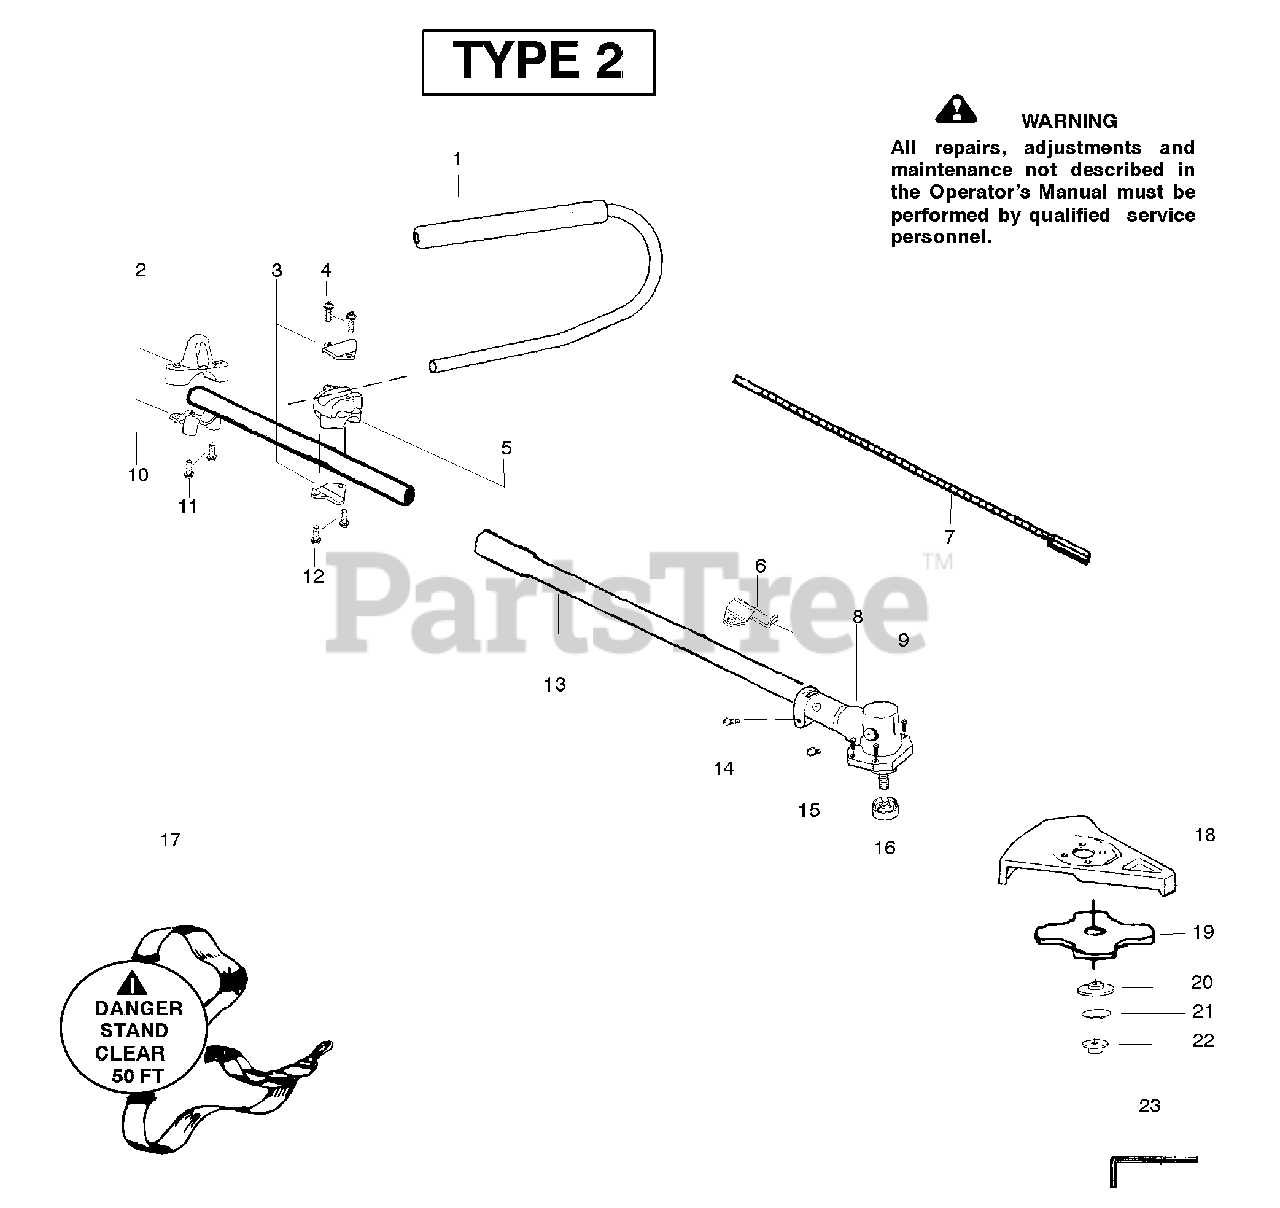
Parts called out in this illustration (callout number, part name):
1	Kit-Handlebar
2	Clamp-Harness Upper
3	Clamp-Bracket
5	Clamp-Handlebar (7/8")
5	Clamp-Handlebar (1")
6	Bracket-Shield
7	Flexshaft-Split boom
8	Assy-Gearbox
10	Clamp-Harness Lower
13	Assy.-Driveshaft
15	Screw-Alignment
16	Dust cup - Blade
17	Assy-Shoulder Strap
18	Kit-Blade Shield
19	Accy.-Weed Blade (8")
20	Washer-Blade Retaining
21	Washer-Belleville
22	Nut-Flange
23	Wrench-Hex (5/32")
